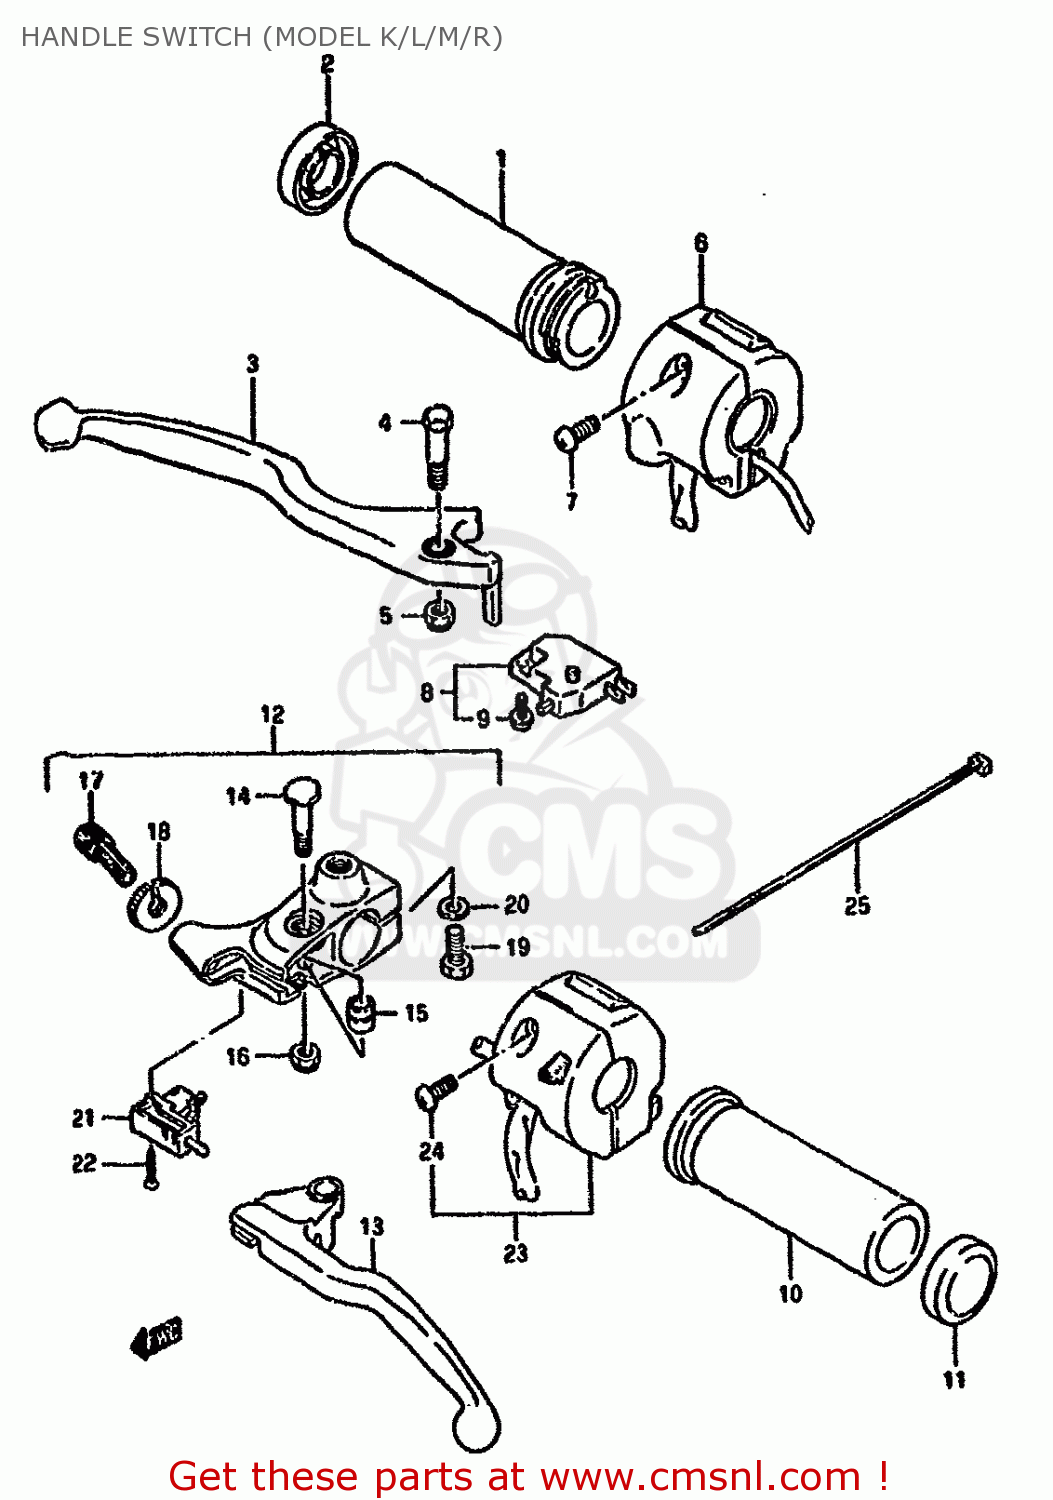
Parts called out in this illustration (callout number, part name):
1	GRIP,THROTTLE
2	CAP,GRIP END
3	LEVER,BRAKE
4	BOLT,LEVER
5	NUT 6MM
6	SWITCH ASSY,HANDLE,R
7	SCREW
8	SWITCH ASSEMBLY,STOP
9	SCREW
10	GRIP,L
11	CAP,GRIP END
12	LEVER ASSEMBLY
13	LEVER,CLUTCH
14	BOLT,CLUTCH LEVER
15	SPACER,CLUTCH LEVER PIVOT
16	NUT 6MM
17	ADJUSTER,WIRE
18	NUT,LOCK
19	BOLT
20	WASHER
21	SWITCH,CLUTCH
22	SCREW
23	SWITCH ASSY,HANDLE LH
24	SWITCH ASSY,HANDLE LH
25	CLAMP
26	CLAMP
